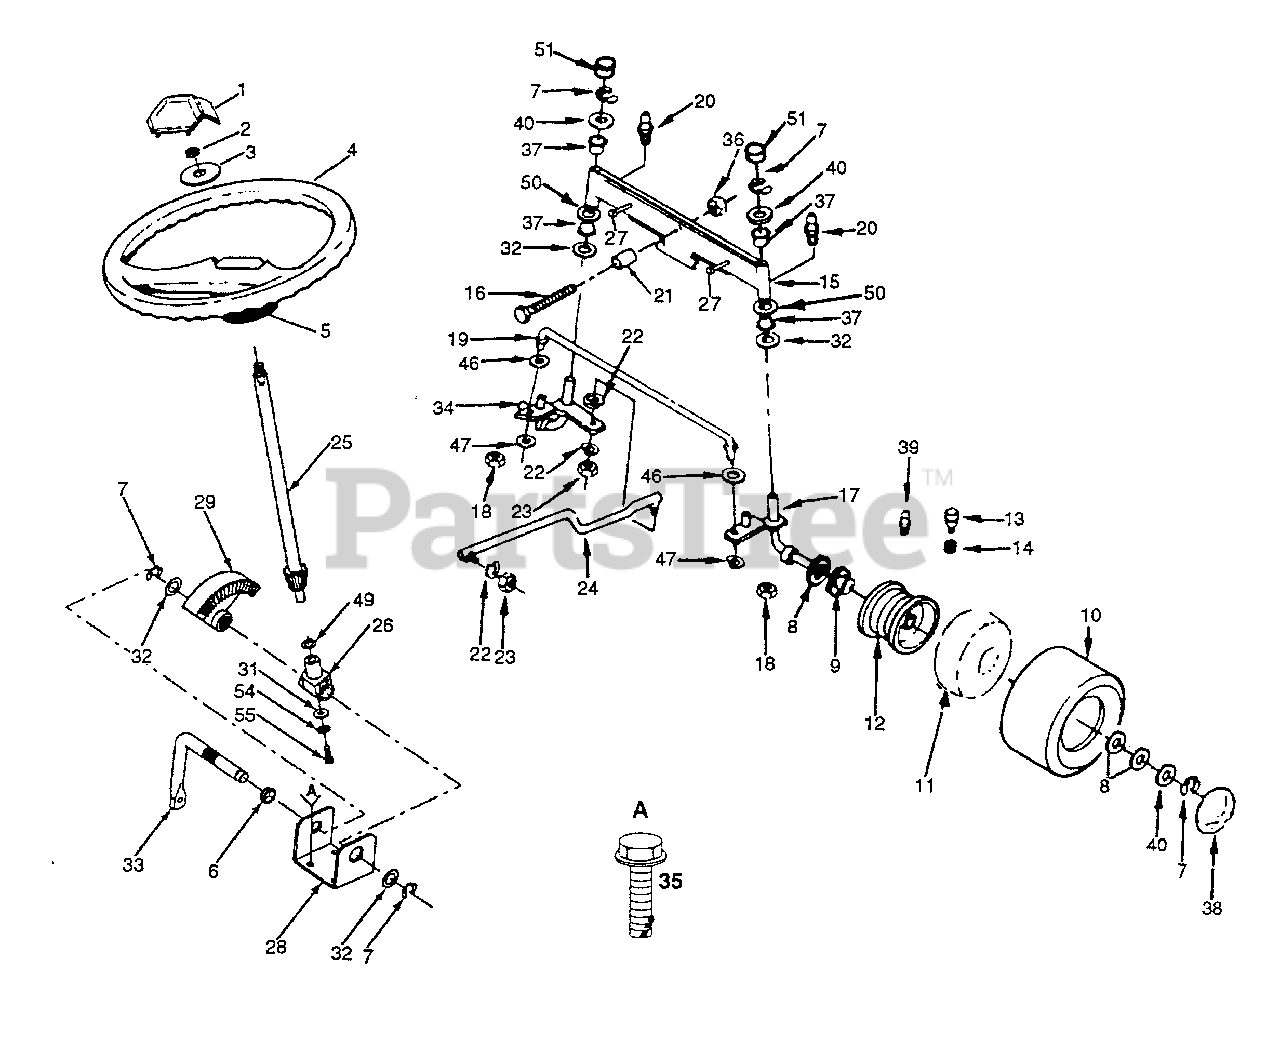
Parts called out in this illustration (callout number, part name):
1	Insert, Steering Wheel
2	Nut, Hex Jam Toplock 1/2-20
3	Washer 17/32 x 2-1/4 x .160
4	Steering Wheel
5	Adapter, Steering Wheel
6	Nyliner, Snap-in
7	Ring, Klip
8	Washer 25/32 x 1-1/4 x 16 Ga.
9	Bearings, Wheel, Front
10	Tire
11	Tube, Tire
12	Rim Assembly
13	Stem, Valve
14	Cap, Valve
15	Axle Assembly, Front
16	Bolt, Hex 5/8-11 UNC x 3-1/2
17	Spindle Assembly, R.H.
18	Nut, Hex Nylon 5/16-24 UNF
19	Tie Rod
20	Fitting, Grease
21	Spacer Bearing, Front Axle
22	Lock Washer 3/8
23	Nut, Hex 3/8-24
25	Shaft, Steering
26	Support Shaft
28	Bracket Assembly, Steering
29	Gear, Sector
31	Washer, Shim
32	Bearing, Thrust
33	Shaft, Pitman
34	Spindle Assembly, L.H.
35	Screw, Hex Washer Hd. Thread Forming Type TT 3/8-16 x 3/4
36	Nut, Flange 5/8 - 11
37	Bearing
38	Cover, Wheel
39	Fitting, Grease
40	Washer 25/32 x 1-5/8 x 16 Ga.
46	Washer 11/32 x 3/4 x 16 Ga.
47	Washer, Lock 1/4
50	Washer 27/32 x -1/4 x 16 Ga.
51	Spindle Cap
54	Washer, Lock
55	Screw, Socket Hex
